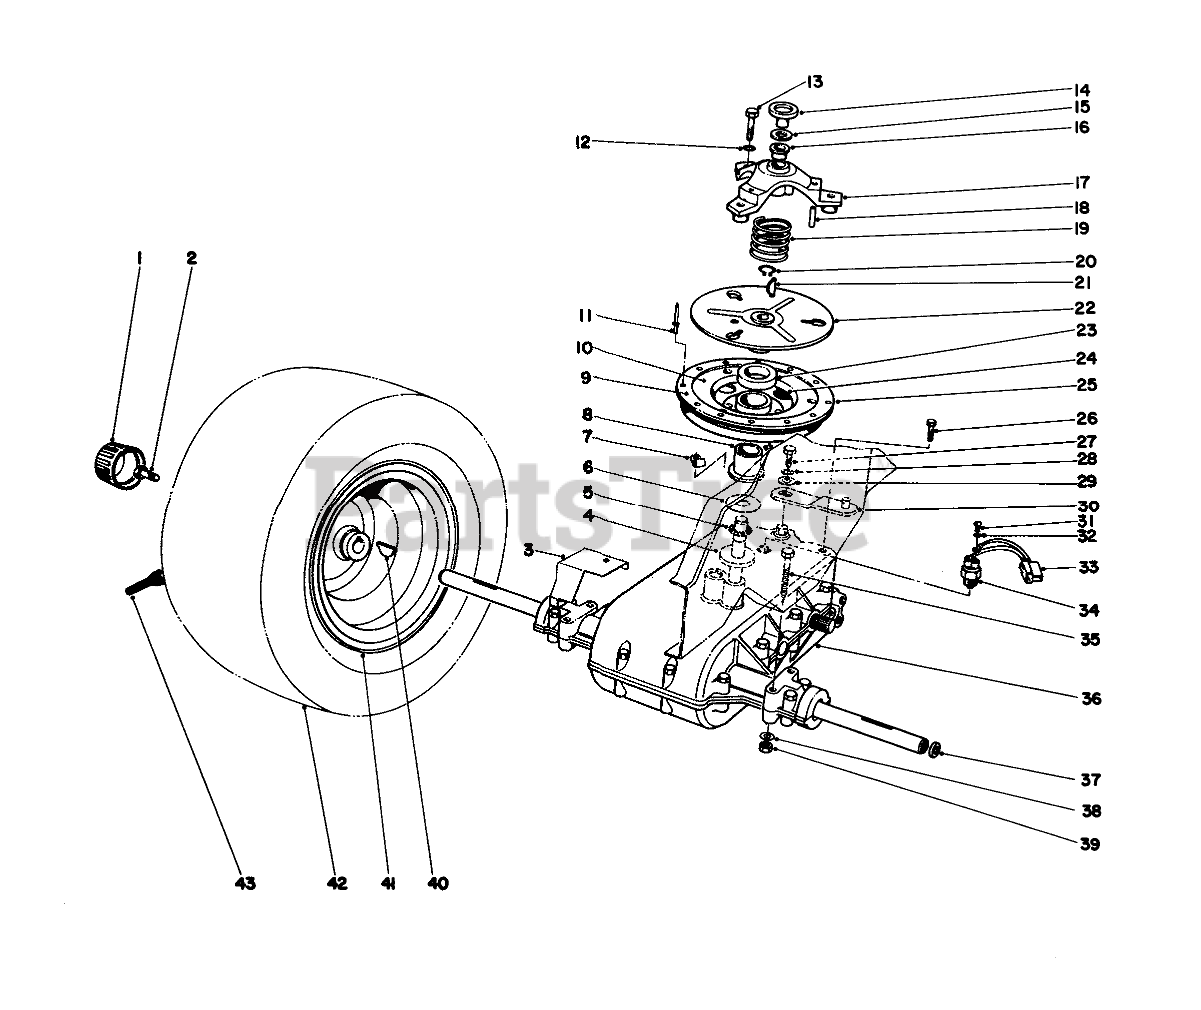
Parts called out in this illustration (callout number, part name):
1	Cap-Hub
2	CAPSCREW 3/8 16 3/4
3	GRASS SHIELD B
4	SPACER
5	NEEDLE BRG
6	THRUST WASHER
7	Clamp (Incl. with Main Wire Harness)
9	CLUTCH PAD
10	RETAINER RING R
11	Rivet
12	WASHER-LOCK
13	SCREW-HH
14	CLUTCH CAP
15	THRUST RACE
16	BUSHING-FLANGE
17	Clutch Cover (Incl. Ref. #16 & 18)
18	NEEDLE BRG
19	COMPRESSION SPRING
20	RING-SNAP, EXTERNAL
21	KEY-WOODRUFF
22	Clutch Plate
23	Felt Washer
25	Sheave Assembly (Incl. Ref. #8-11)
26	SCREW-HWHTF
27	SCREW-HH
28	WASHER-LOCK
29	WASHER-FLAT
30	SHIFT LEVER WA B
31	SCREW
32	WASHER-LOCK/INT
33	WIRE HARNESS
34	NEUTRAL SWITCH
35	SCREW-HH
36	Transaxle
37	SPACER-WHEEL
38	WASHER-PLAIN
39	NUT-LOCK, NI
41	WHEEL ASM
43	STEM-VALVE
